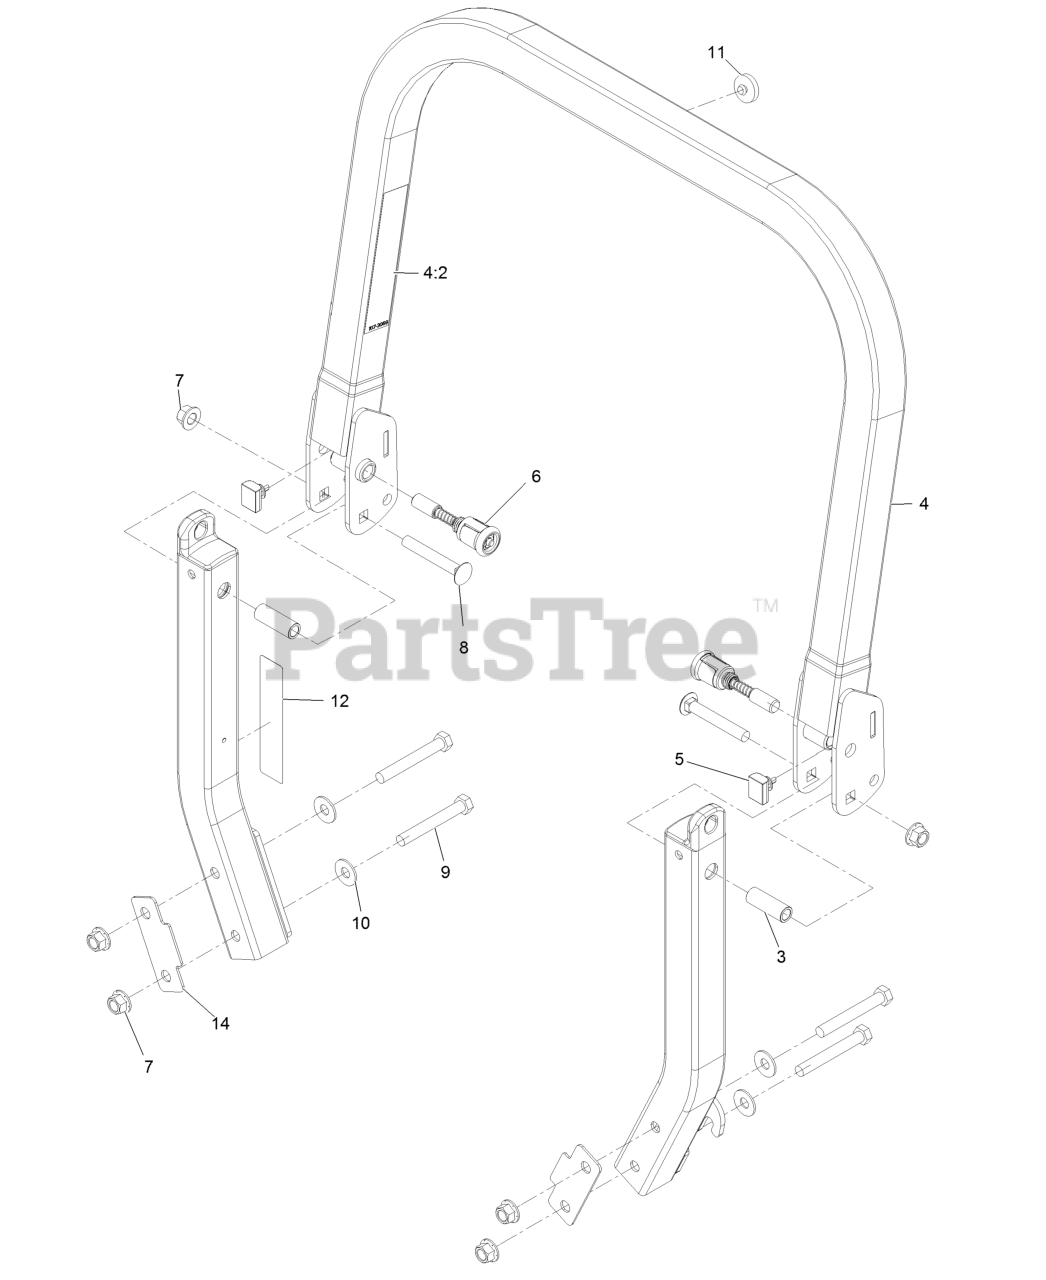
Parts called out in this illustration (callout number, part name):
4	Upper ROPS ASM
4:2	Decal-Warning
5	Bumper-ROPS
6	Pin-Spring
7	Nut-Lock 1/2-13
8	Bolt-Carriage 1/2-13 X 3 1/2
9	Screw-HH
10	Washer, Spring Disc 1/2
11	Bumper-Push-In, Rubber
12	Decal-Caution, Fuel Vent
